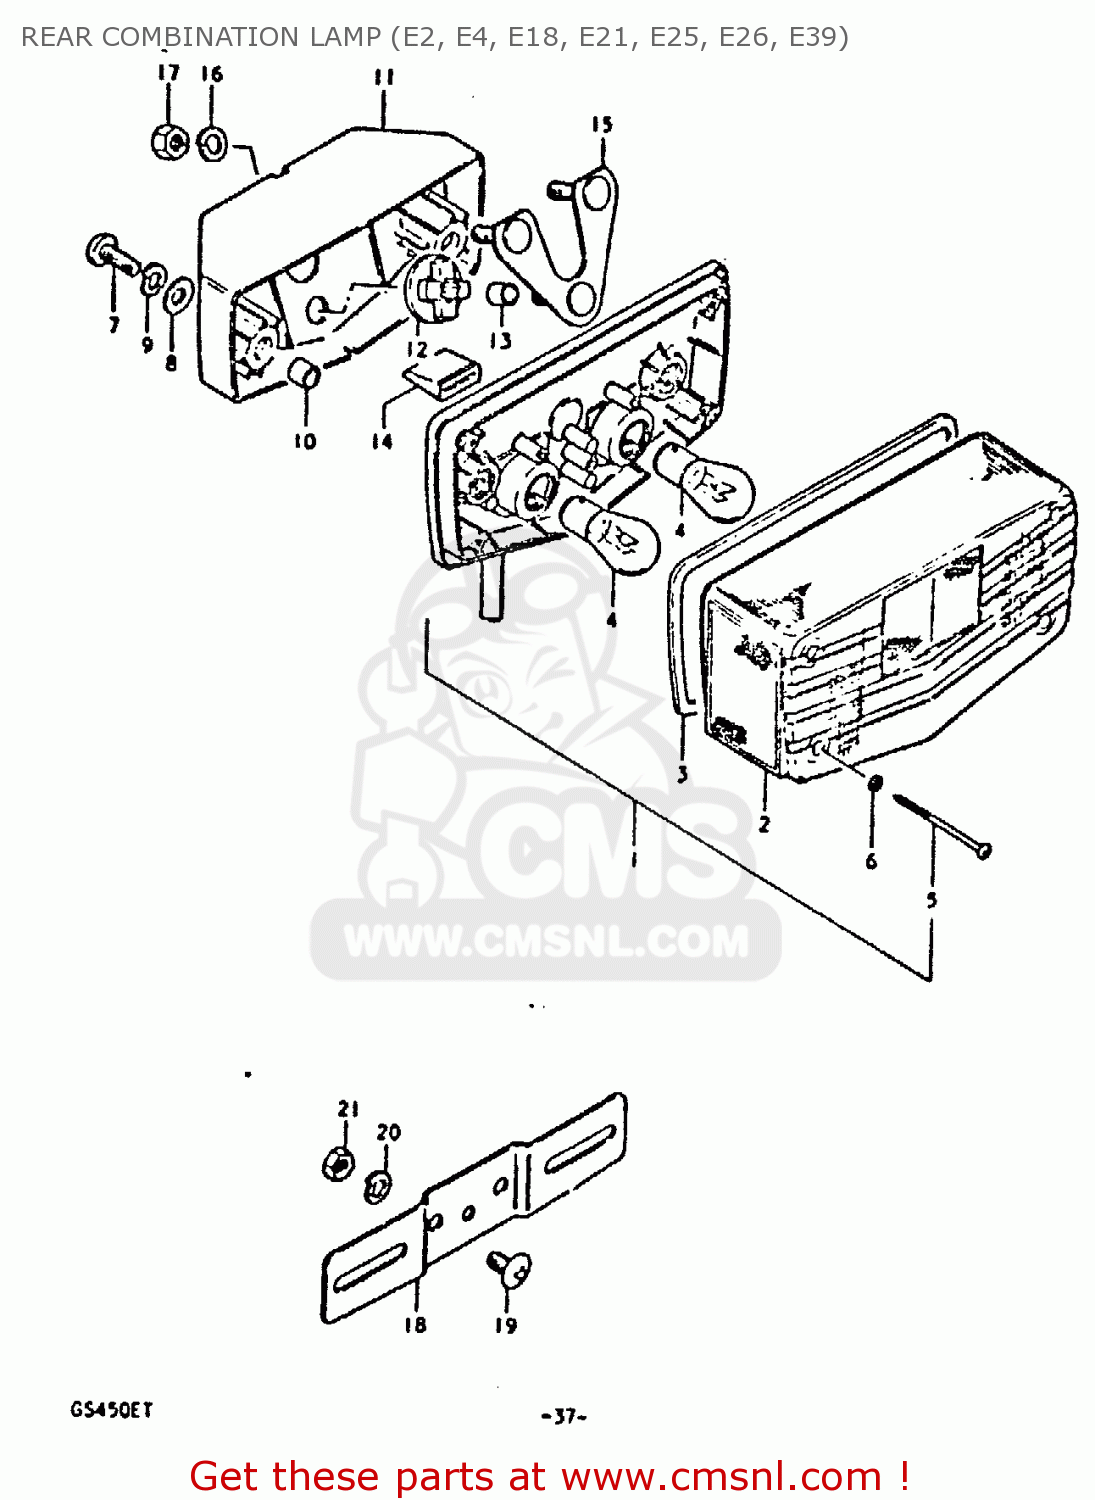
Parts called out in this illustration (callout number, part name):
1	LAMP UNIT, TAIL
2	LENS
3	GASKET,REAR COMBINATION LAMP LENS (NAS)
4	BULB 12V21/5W
5	SCREW
6	GASKET
7	SCREW
8	WASHER
9	LOCK WASHER
10	SPACER,REAR COMBINATION LAMP
11	BRACKET UNIT,TAIL LAMP
12	CUSHION,REAR COMBINATION LAMP
13	SPACER,REAR COMBINATION LAMP
14	CUSHION,REAR COMBINATION LAMP
15	PLATE,REAR COMBINATION LAMP
16	LOCK WASHER
17	NUT
18	PLATE,RR LICENSE
19	SCREW
20	LOCK WASHER
21	NUT
